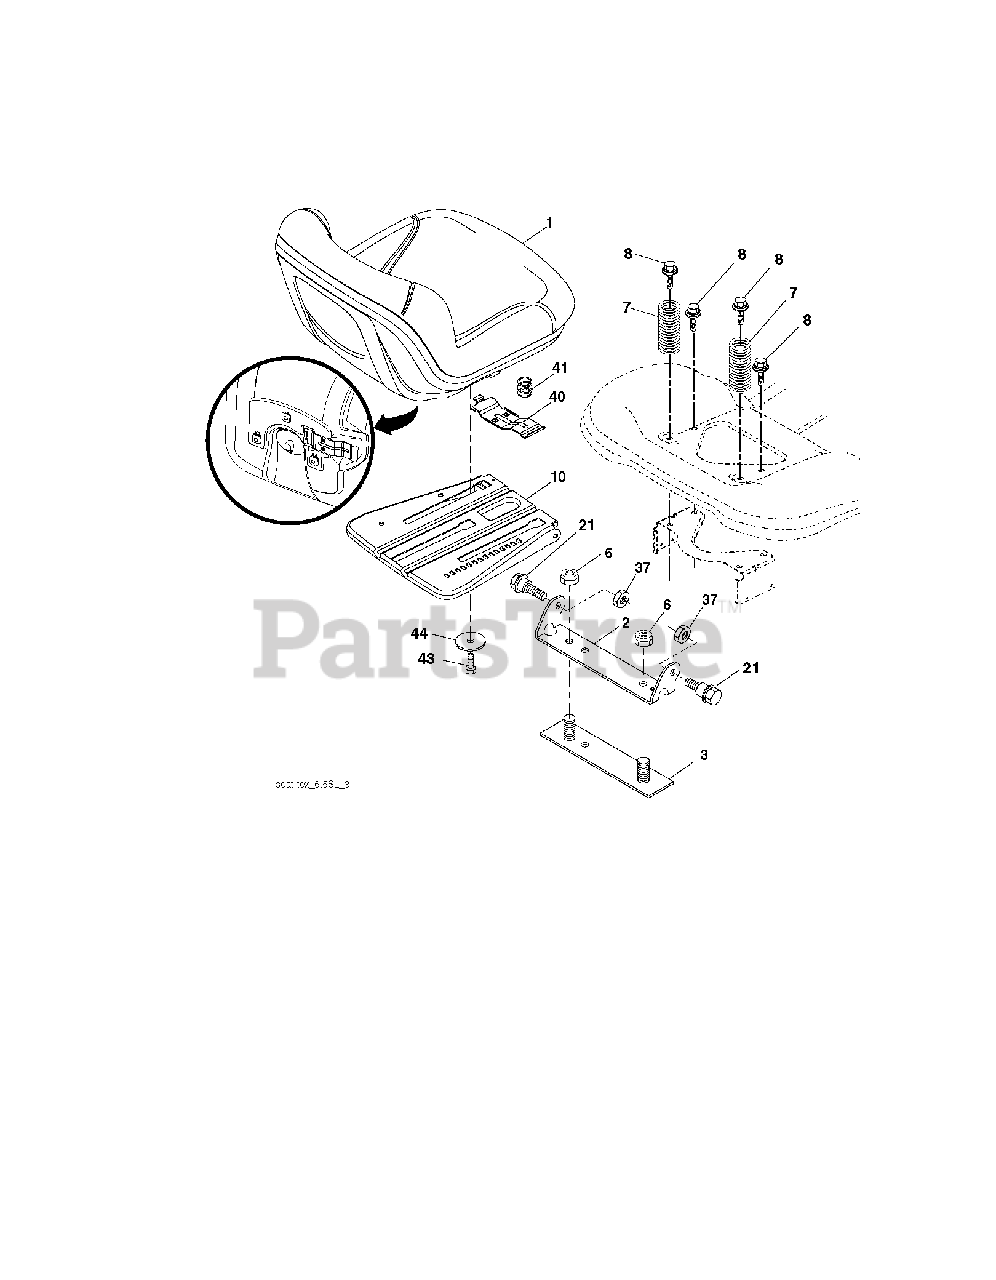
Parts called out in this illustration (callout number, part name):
1	RP SEAT, TH150, GREY, MILSCO
2	BRKT.PIVOT.FENDER
3	STRAP
6	NUT
7	SPRING COMPRESSION
8	BOLT, 5/16-18 X 1 3/4
10	PAN.ASM.SEAT.3PT
21	BOLT.SHOULDER.5/16-18
37	NUT.71038.31-18.HEX.NYLOCK
40	HANDLE.SLIDE.SEAT.TEX.BLACK
41	SPRING.LATCH.SEAT.TEX
44	WASHER 13/32 X 2-3/8 X 12GA
